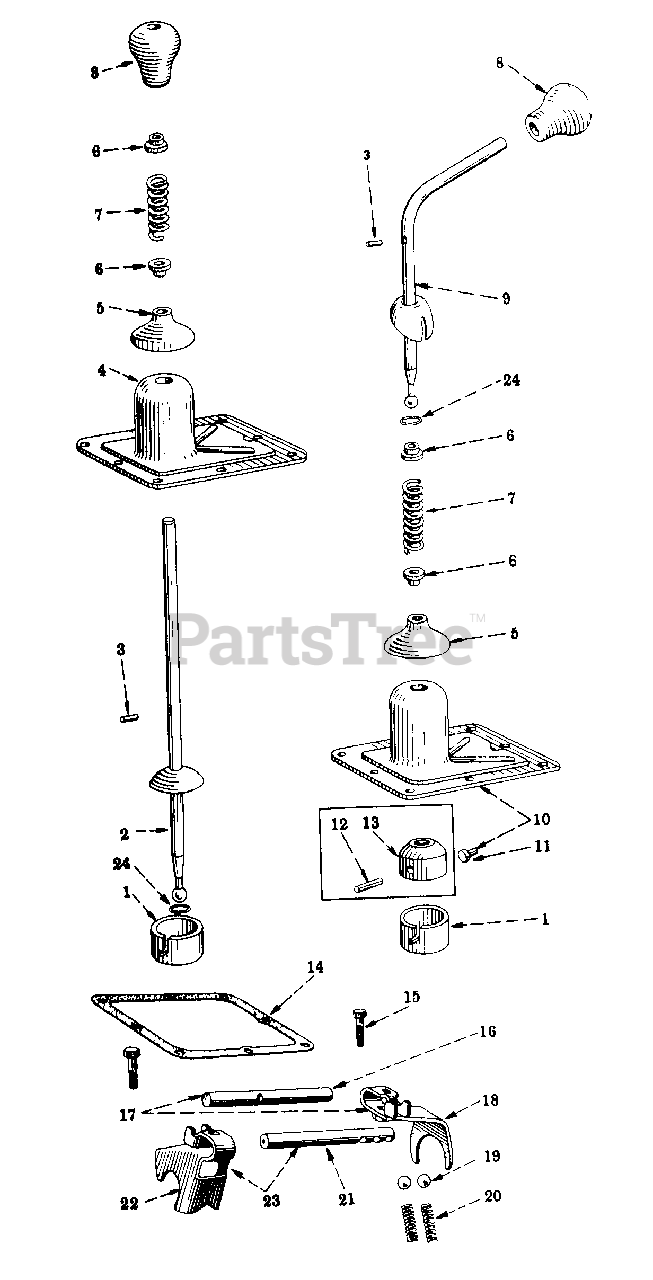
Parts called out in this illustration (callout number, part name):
1	GUIDE, GEAR SHIFT LEVER
2	LEVER ASSY, GEAR SHIFT
3	PIN, GEAR SHIFT SWIVEL SPRING RETAINER
4	HOUSING GEAR SHIFT LEVER
5	SHIELD, GEAR SHIFT LEVER
6	RETAINER GEAR SHIFT SWIVEL SPRING
7	SPRING GEAR SHIFT SWIVEL
8	KNOB, GEAR SHIFT LEVER
9	LEVER ASSY, GEAR SHIFT
10	HOUSING W/PIN, IH-364066-R1, GEAR SHIFT LEVER
11	PIN, GEAR SHIFT LEVER SWIVEL STOP
12	PIN, 3/16 X 1-1/2 ROLL
13	SWIVEL, GEAR SHIFT LEVER
14	GASKET, GEAR SHIFT LEVER HOUSING
15	SCREW, SHIFTER FORK
16	ROD, SECOND AND THIRD SPEED SHIFTER
17	FORK ASSY, SECOND AND THIRD SPEED SHIFTER
18	FORK W/SCREW, IH-351543-R2 AND WASHER, IH-103320.
19	BALL. 3/8 DIAMETER CR-STL - GEAR SHIFTER POPPET
20	SPRING GEAR SHIFTER POPPET
21	ROD, FIRST AND REVERSE SPEED SHIFTER
22	FORK W/SCREW, IH-351543-R2 AND WASHER IH-103320.
23	FORK ASSY, FIRST AND REVERSE SPEED SHIFTER
24	O-RING, 1/2 X 5/8 X 1/16 - GEAR SHIFT LEVER
